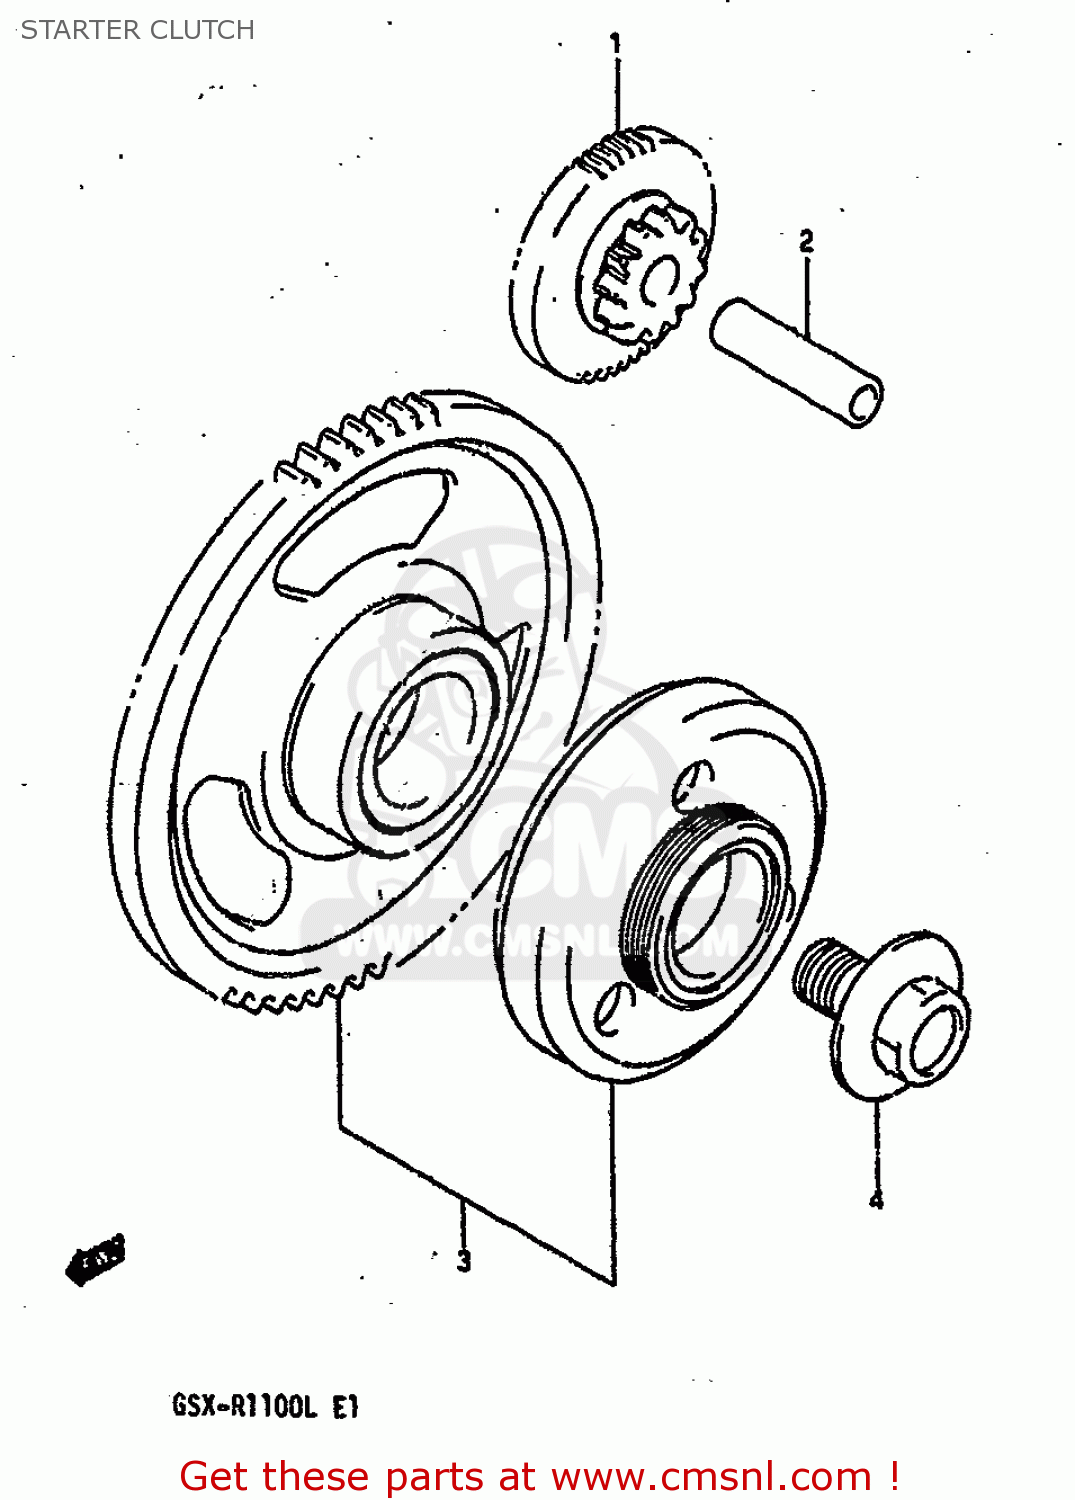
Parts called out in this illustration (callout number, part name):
1	GEAR,STARTER IDLE(NT:12,53)
2	PIN(7X11X42)
3	CLUTCH SET,STARTER
4	BOLT(14X21)
